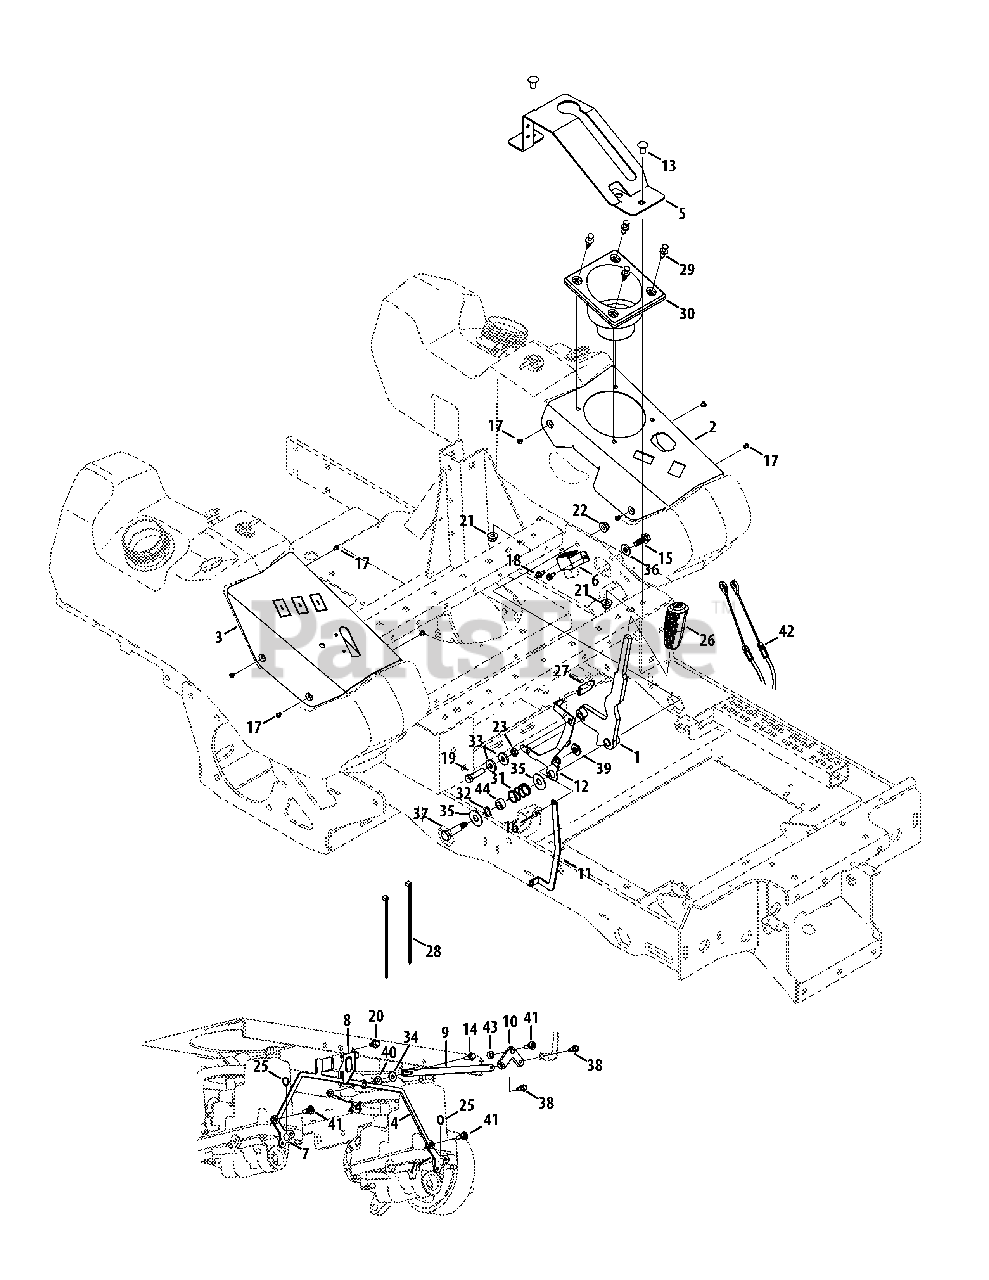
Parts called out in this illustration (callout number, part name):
1	Brake Handle Assembly
2	LH Control Panel
3	RH Control Panel
4	Dump Valve Actuator Bracket
5	Boot Brake Bracket
6	Brake Switch Mount
7	Transmission Bypass Lever
8	Neutral Switch Bracket
9	Transmission Link Arm
10	Neutral Pivot Control Lever
11	Neutral Arm
12	Dump Valve Release Lever
13	Carriage Bolt, 3/8-16 x .75
14	Hex Flange Screw, 1/4-20 x .75
15	Screw, 3/8-16 x 1.00
16	Screw, M6 x 8mm
17	Machine Screw, #10-32 x .25
18	Hex Flange Screw, 1/4-20 x .500
19	Hex Cap Screw, 3/8-16 x 1.50
20	Screw, 5/16-18 x .50
21	Nut, 3/8-16, Flangelock
22	Nut, 3/8-16, Flangelock
23	Jam Nut, 3/8-16
24	Nut, 1/4-20, Hexflange
25	Retainer Ring
26	Grip, .50 ID
27	Grip, Seat, Adjustment (Yellow)
28	Cable Tie
29	Rivet, .3125
30	Cup Holder
31	Compression Spring, .844 x .97 x 1.5
32	Washer, Wave, .531 x .781 x .013
33	Flat Washer, .385 x 1.00 x .135
34	Flat Washer, .283 x .750 x .030
35	Flat Washer, .508 x 1.325 x .040
36	Flat Washer, .406 x .875 x .105
37	Shoulder Screw, .498 x 1.445
38	Shoulder Screw, .342 x .335, 1/4-28
39	Shoulder Spacer, M6
40	Shoulder Spacer, .375 x .625 x .20
41	Shoulder Screw, .375 x .280, 1/4-14
42	Brake Cable
43	Spacer, .256 x .500 x .240
44	Spacer, .51 x .75 x .390
